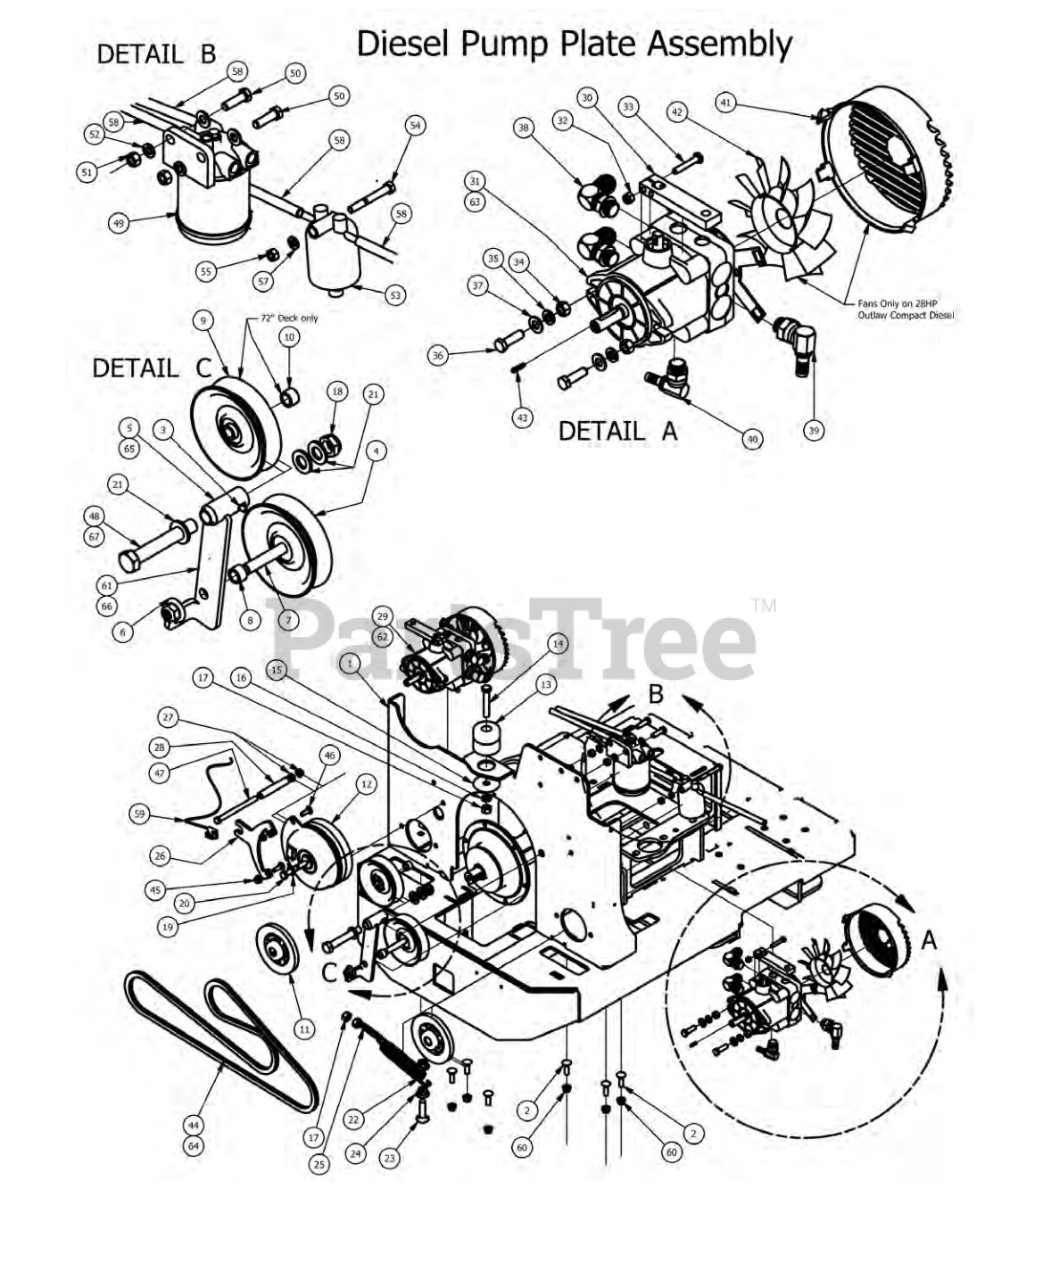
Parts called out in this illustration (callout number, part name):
1	Pump Plate Diesel
2	3/8" x 1 1/4" Carriage Bolt
3	1/4" Drive in Grease Fitting
4	43/4" Idler Pulley
5	Pump Idler Bracket only for 61" Deck
6	1/2-13 Nylon Flange Nut-Orange
7	1/2" x 3" Hex Bolt
8	1/2 x 1/2 Spacer
9	5 Idler Pulley only for 72" Deck Diesel
10	5/8" x 1/" Collar Spacer only for 72" Deck Diesel
11	5 Pump Pulley
12	Clutch Assembly for Diesel
13	Armor Plated Mount-Rear Mount
14	1/2" x 3" Hex Bolt
15	Snubbing Washer
16	1/2" Lock Washer
17	1/2" Hex Nut
18	5/8" Nylock (1/2 Jam)
19	7/16" Lock Washer
20	7/16" x 2 3/4" Fine Thread Bolt
21	.630 ID x 1.122 OD x .142 THK Plastic Washer
22	Deck Idler Spring
23	1/2 x 2" Carriage Bolt
24	1/2-13 Nylon Flange Nut-Orange
25	1/2-13 x 2-1/2 All Thd Stud
26	Diesel PTO Engager Holder
27	3/8" Flange Nut
28	3/8 hase 4" long
29	PR Pump W/Fan Left -28Hp Diesel
31	PR Pump with Fan and Cover Right -28Hp Diesel
32	1/4" Nylock Nut
33	1/4" x 1 1/2" Bolt
34	3/8" Hex Nut
35	3/8" Lock Washer
36	3/8" x 1 1/2" Hex Bolt
37	3/8" Flat Washer
38	6801-LL-8-8 Fitting- Compact Diesel
39	90 Degree Fitting 1/2" x 3/4" 4601-8-8
40	90 Degree Fitting 3/8" X 9/16"-4601-6-6
41	Fan Guard for 10A
42	Hydraulic Fan
43	5mm x 1.25" Key
44	Pump Belt 28Hp Diesel
45	5/16" Flange Nut
46	5/16" x 1" Carriage Bolt
47	3/8-16 x 5 Hex Bolt- Grade 5
48	5/8" x 4" Hex Bolt 61° Deck only
49	Fuel Filter
50	3/8" x 1 1/4" Hex Bolt
51	3/8" Hex Nut
52	3/8" Lock Washer
53	Caterpillar Fuel Bowl Kit
54	5/16" x 2 1/2" Bolt
56	5/16" Flat Washer
57	5/16" Lock Washer
58	5/16" fuel line hose
59	Clutch Pigtail
60	3/8" Nylock Flange Nut
61	Pump Idler Assembly Components 3,4,5,6,7,8, only for 61" Deck
62	Left Pump 16cc-AOS Diesel 35Hp Diesel
63	Right Pump 16cc-AOS Diesel 35Hp Diesel
64	Pump belt for 35HP Diesel
65	Diesel Pump Idler only on 72" Deck
66	Diesel Pump Idler Assembly Components 3,4,5,6,7,8,9,10 only for 72" Deck
67	5/8 x 5 1/2 Bolt only for 72" Deck
